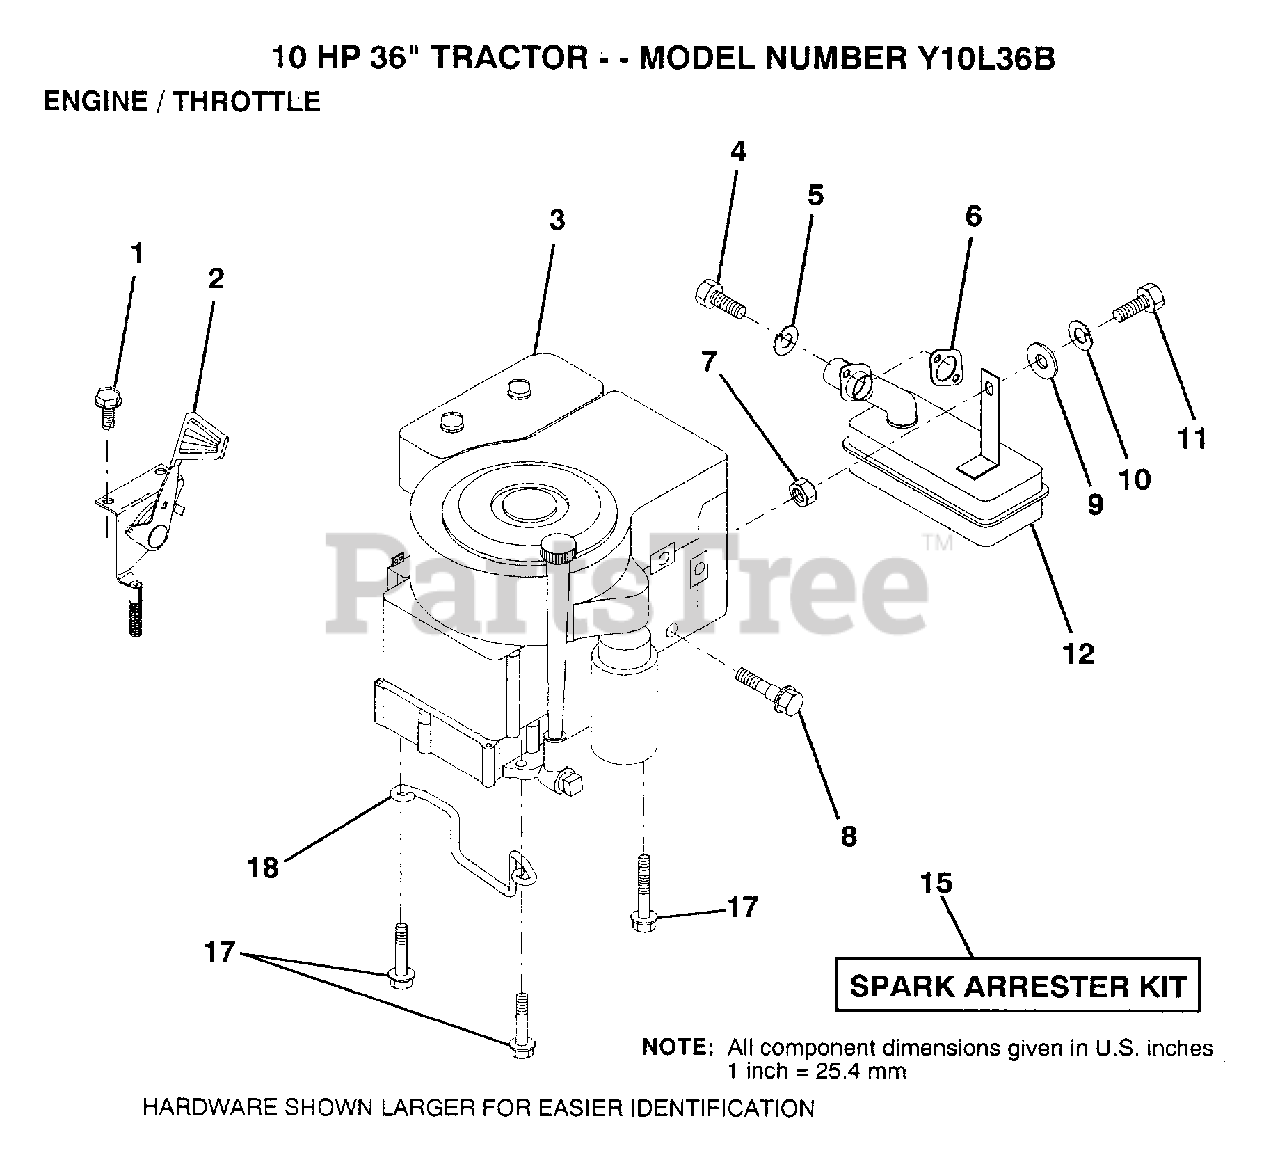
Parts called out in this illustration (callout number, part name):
1	SCREW.1/4-20X1/2
2	"CONTROL,THROTTLE"
3	ENGINE, B&S 10 HP
4	SCREW
5	LOCKWASHER
7	NUT.HEX.5/16-18
8	BOLT T
10	LOCKWASHER
11	BOLT
12	MUFFLER
17	SCREW LT
18	"KEEPER,DR BELT GR"
